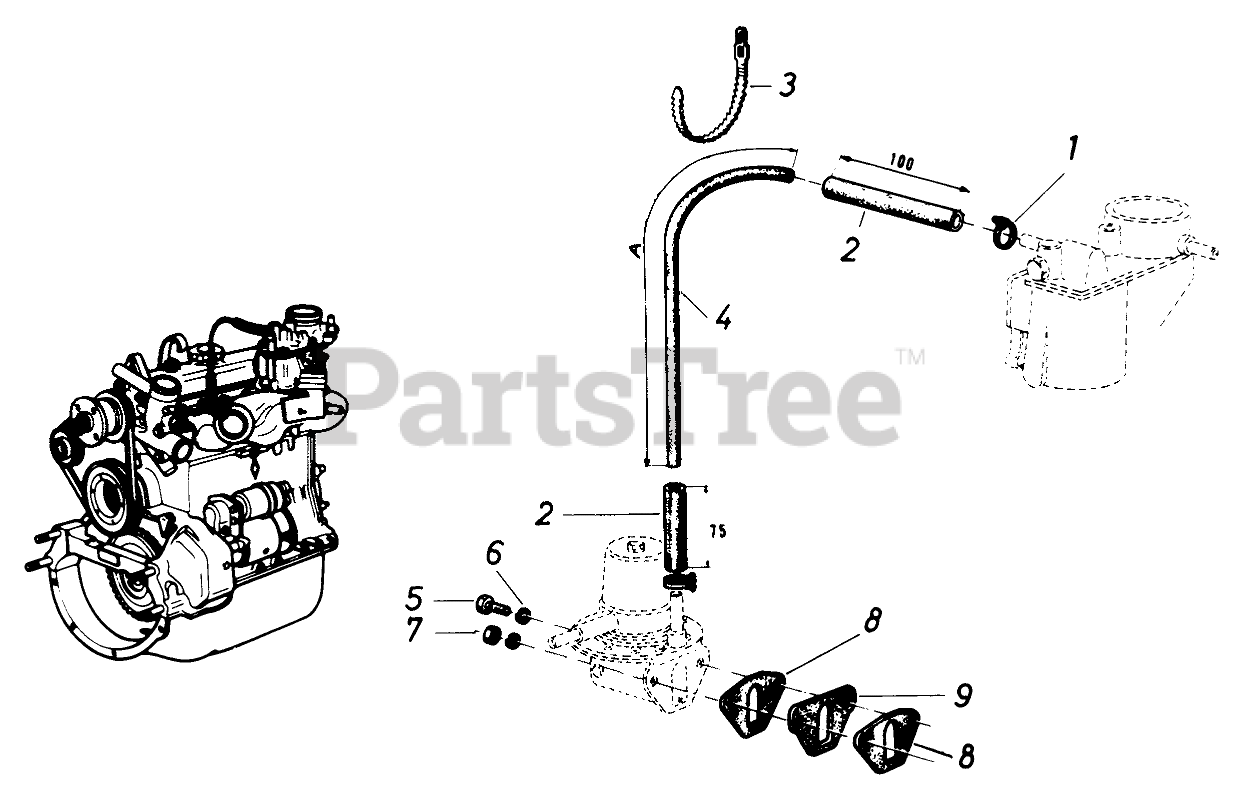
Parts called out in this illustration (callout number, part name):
1	Clamp
2	Joining Hose
3	Fastening Strap
4	Fuel Pipe (A305)
5	Screw
6	Lock Washer
8	Gasket
9	Insulating Plate
